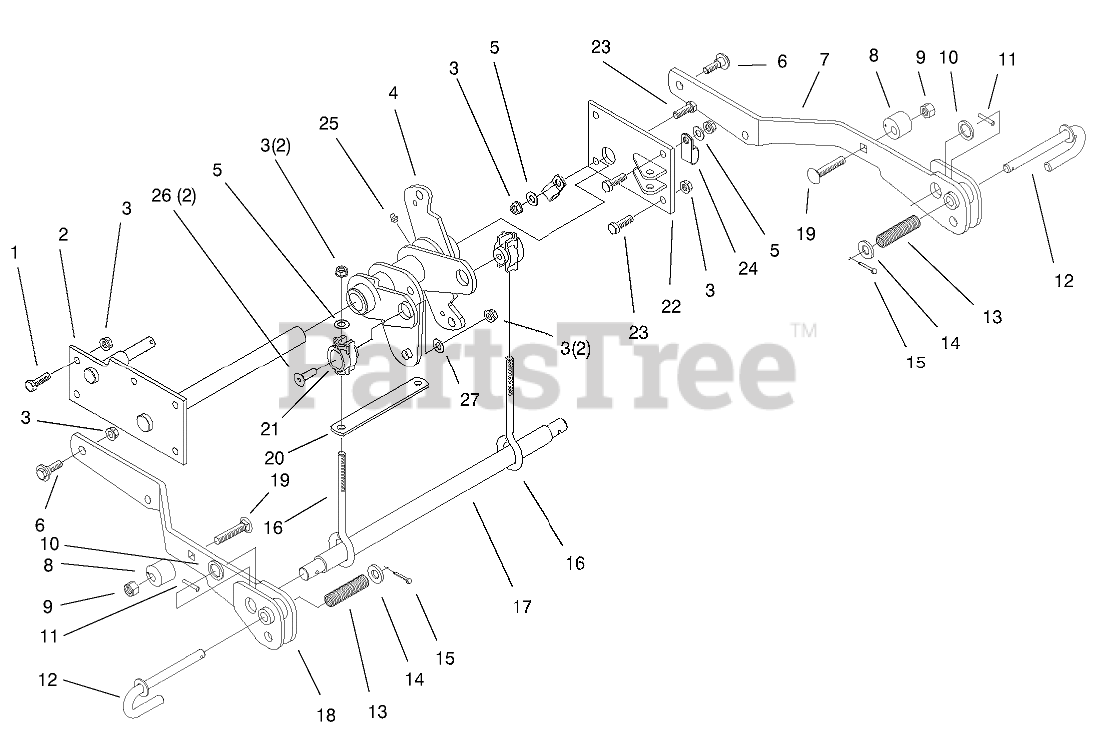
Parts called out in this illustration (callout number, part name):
1	SCREW-HH
2	SUPPORT-LIFT, DECK
3	NUT-LOCK, NI
4	BELLCRANK AND BUSHING ASM
5	Washer-Flat (only on: 73471, 73542)
6	BOLT-SHOULDER
7	ARM-LIFT, LH
8	STOP-LIFT, ADJ.
9	NUT-LOCK, NI
10	WASHER-FLAT
11	PIN-ROLL
12	PIN - J
13	SPRING-COMPRESSION
14	WASHER-FLAT
15	PIN-COTTER
16	ROD - LIFT
17	BAR-LIFT
18	Arm-Lift, RH
19	SCREW-CARR
20	SPACER-STRAP
21	SLEEVE-LIFT
22	PLATE - LH SUPPORT
23	SCREW-HH
24	CLAMP-TUBE
25	FITTING-GREASE
26	SCREW-HSFH
27	WASHER-FLAT
